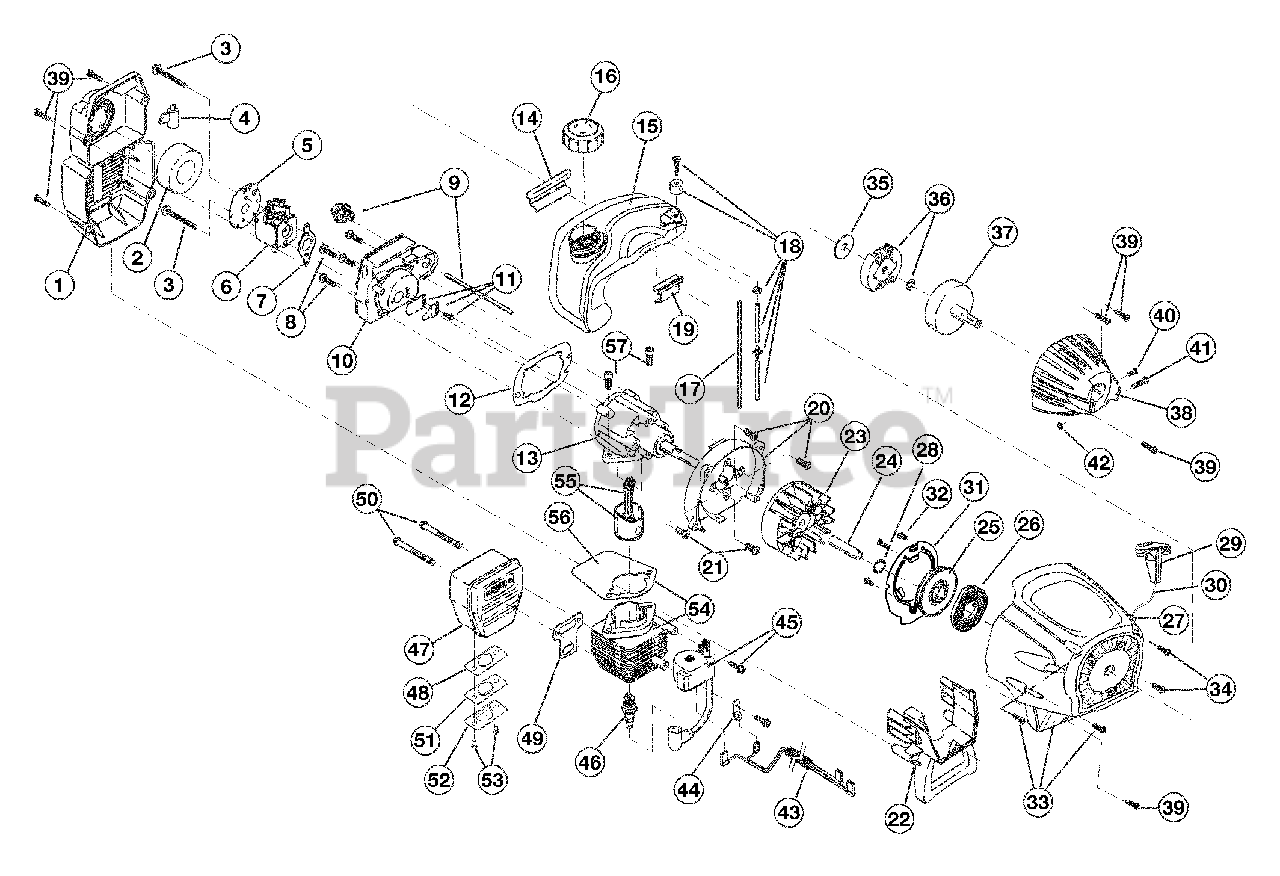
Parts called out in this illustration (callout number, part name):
1	Air Cleaner/Muffler Cover Assembly
2	Air Cleaner Filter
3	Carburetor Mounting Screw Assembly
4	Choke Extension
5	Choke Plate
6	Carburetor Assembly
7	Carburetor Gasket
8	Carb Mount Screw
9	Primer & Hose Assembly
10	Carb Mount Assembly
11	Reed Assembly
12	Carburetor Mount Gasket
13	Crank Case Service Assembly
14	Rear Mounting Pad
15	Fuel Tank Assembly
16	Fuel Cap Assembly
17	Fuel Return Line
18	Fuel Line Assembly
19	Front Mounting Pad
20	Shroud Assembly
21	Shroud Screw
22	Shroud Extension & Stand
23	Flywheel Assembly
25	Recoil Pulley Assembly
26	Recoil Spring
27	Rope Guide
28	Pulley Retainer
29	Pull Handle
31	Pressure Plate Assembly
32	Plate Screw
33	Starter Housing Assembly
34	Housing Screw
35	Clutch Washer
36	Clutch Rotor Assembly
37	Clutch Drum Assembly
38	Clutch Cover Assembly
39	Cover Screw
40	Anti-Rotation Screw
41	Clamping Screw
42	Clamping Nut
43	Wire Leads and Sleeve
44	Ground Tab
45	Module Assembly
47	Muffler Assembly
48	Spark Arrestor Screen
49	Exhaust Gasket
50	Muffler Mounting Bolt Assembly
51	Spark Arrestor Plate
52	Spark Arrestor Hood
53	Spark Arrestor Screw
54	Cylinder Assembly
55	Piston and Rod Assembly
56	Cylinder Gasket
57	Cylinder Bolt
